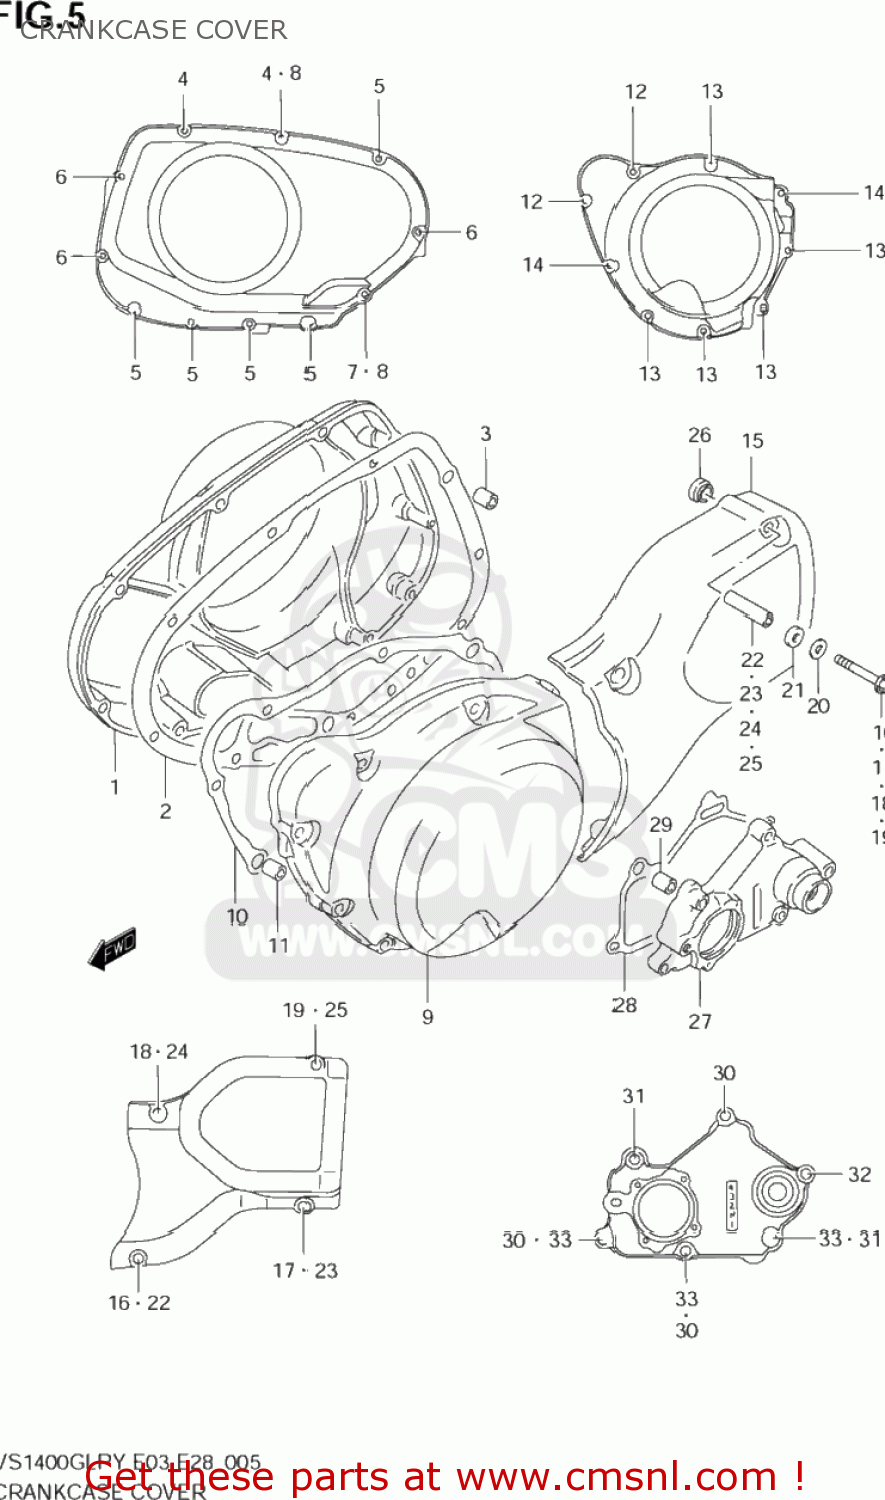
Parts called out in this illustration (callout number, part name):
1	COVER,CLUTCH
2	GASKET,CLUTCH COVER (NAS)
3	PIN
4	BOLT
5	BOLT
6	BOLT
7	BOLT
8	GASKET(5.8X11X1.2) (NAS)
9	COVER,GENERATOR
10	GASKET,GENERATOR COVER (NAS)
11	PIN(8.4X11X20)
12	BOLT
13	BOLT
14	BOLT
15	COVER,SECONDARY GEAR CASE
16	BOLT
17	BOLT
18	BOLT
19	BOLT
20	WASHER
21	WASHER(8.7X16X5)
22	SPACER(6.5X9X21)
23	SPACER(6.5X9X26)
24	SPACER(6.5X9X49)
25	SPACER (L=45.9)
26	WASHER(8.7X16X5)
27	COVER,GEAR SHIFT
28	GASKET,GEAR SHIFT COVER (NAS)
29	PIN
30	BOLT
31	BOLT
32	BOLT
33	GASKET(5.8X11X1.2) (NAS)
